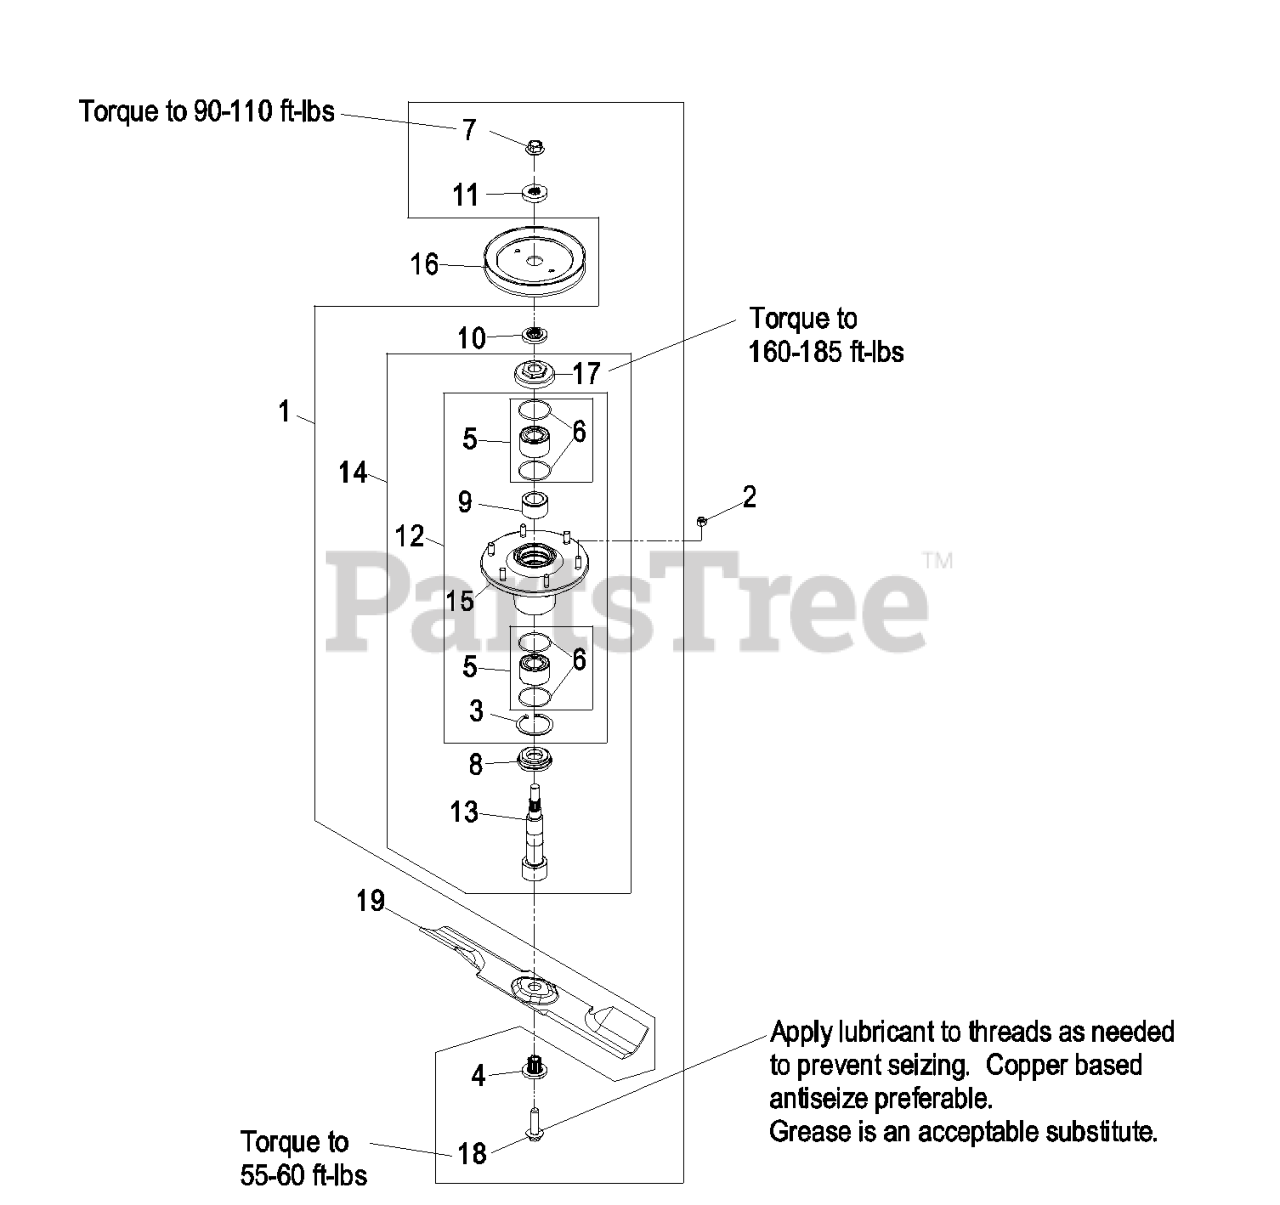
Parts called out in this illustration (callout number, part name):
1	ASM, CUTTER HSG W/MNT HRD
2	NUT-LOCK, NI
3	RING-RETAINING
4	BUSHING,SPLINED
5	ASM, BEARING W/ORINGS
7	NUT-FLANGE, CENTERLOCK
8	GUARD,BOTTOM
9	SPACER,BEARING
10	SPACER,SPLINED STEPPED
11	SPACER,SPLINED
12	ASM,CUTTER HOUSING
15	ASM,HOUSING W/STUDS
